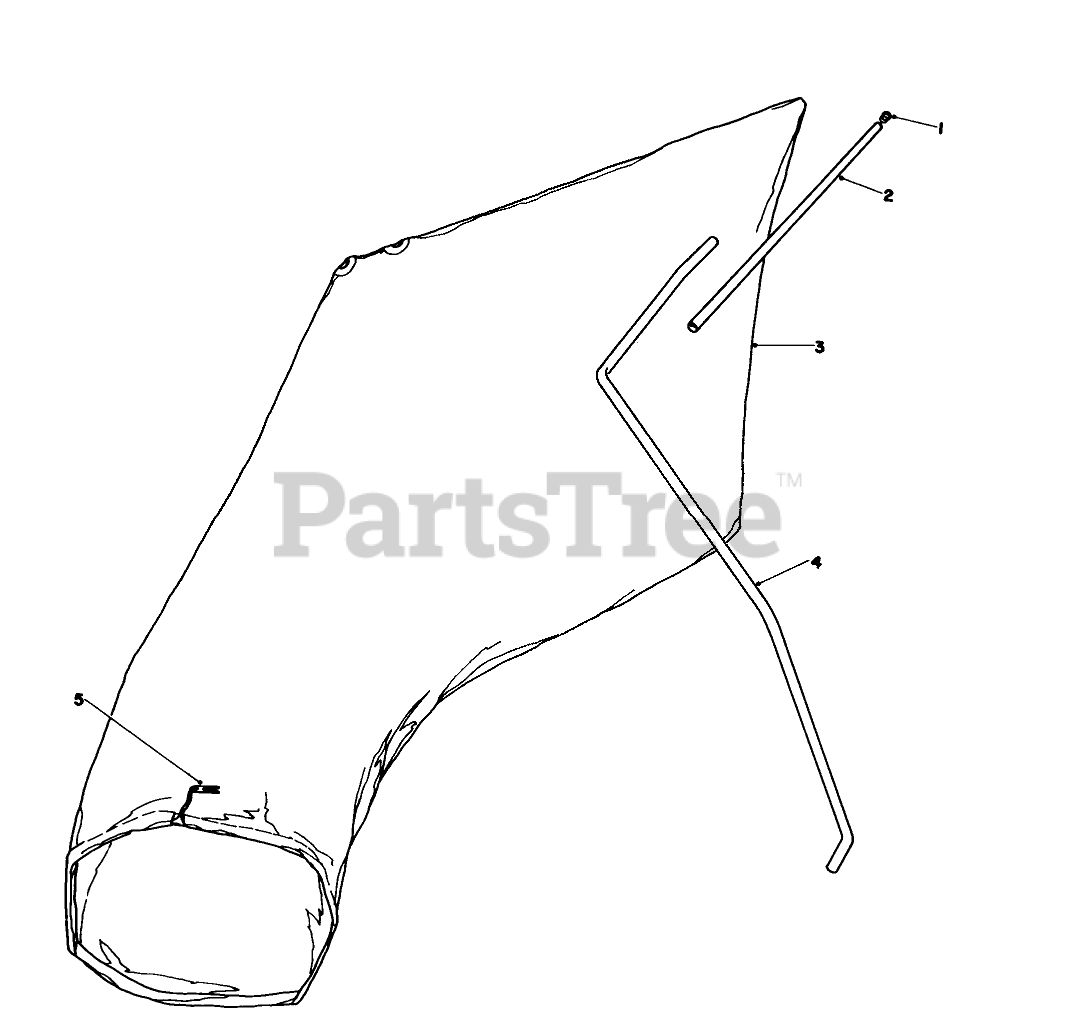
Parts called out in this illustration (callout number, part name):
2	BAG HANGER TUBE
3	Bag (Incl. Ref. #5)
4	HANGER ROD
5	BAG CORD FASTENER
